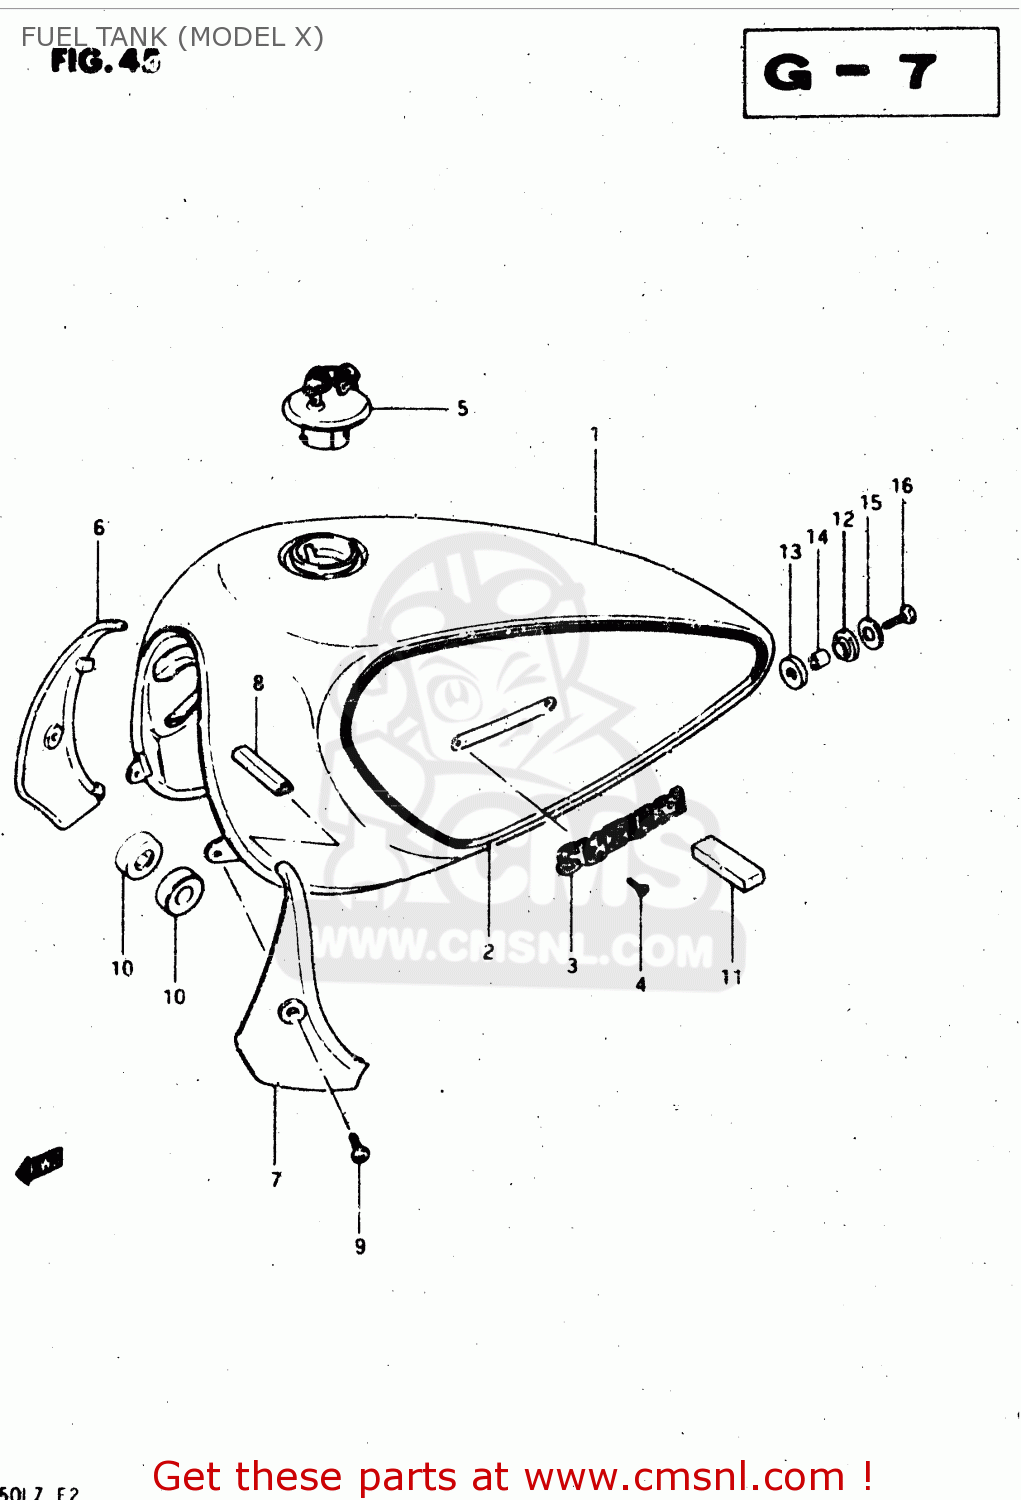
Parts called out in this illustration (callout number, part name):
1	TANK ASSEMBLY,FUEL
2	TAPE SET,FUEL TANK
3	EMBLEM,FUEL TANK
4	SCREW 3X6
5	CAP SET,FUEL TANK
6	COVER,FUEL TANK,FRONT,RIGHT
7	COVER,FUEL TANK,FRONT,LEFT
8	TUBE, FRONT
9	SCREW 6X12
10	CUSHION
11	CUSHION
12	CUSHION
13	CUSHION
14	SPACER(8.5X12X19)
15	WASHER (8.5X29X1.6)
16	BOLT (8X30)
